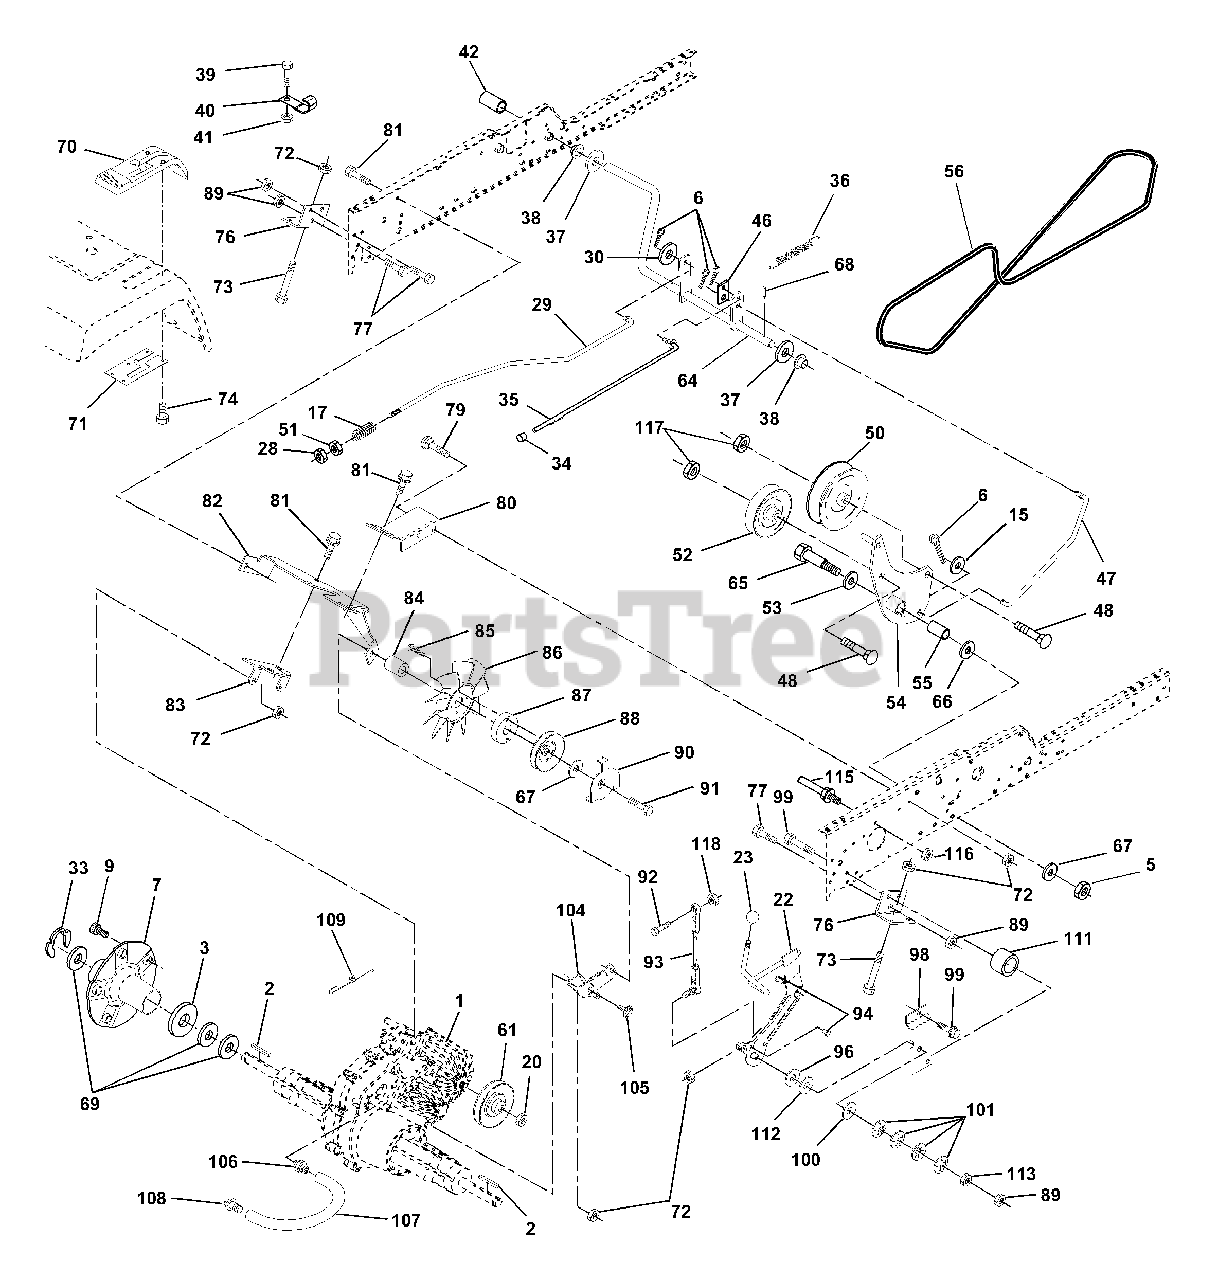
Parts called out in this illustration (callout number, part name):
2	Key 1/4 x 2.5
3	Washer Thrust Axle Harden
5	Nut Crownlock 3/8-16
6	Pin Cotter 1/8 x 3/4
7	Wheel Hub Asm.
9	Bolt Hub
15	Washer 13/32 x 13/16 x 16 Ga
17	Spring Rod Brake
20	Nut Hex Jam Toplock 1/2-20
22	Shift Arm Asm
23	Knob
28	Nut Hex Jam 3/8-16
29	Brake Rod
30	Washer 13/32 x 1 x 16 Ga.
33	Ring E
34	Cap Brake Parking
35	Rod Parking Brake
36	Spring Drive Ground
37	Washer 25/32 x 1-1/4 x 16 Gauge
38	Nyliner, Bushing
39	Screw Fin #10-24 x 1
40	Actuator Interlock Switch
41	Nut Lock #10-24
42	Cover Pedal
46	Retainer Spring
47	Clutch Rod
48	Bolt Carriage 3/8-16 x 1-1/2 Gr 5
50	Pulley Idler Flat
51	Nut Crownlock 3/8-16 UNC
52	Pulley Idler Grooved
53	Washer Hartdened
54	Clutch Arm Asm
55	Bearing, Idler
56	V-Belt
58	Bolt Fin Hex 7/16-14 x 1-1/2
61	Pullery Transaxle
64	Shaft Asm Brake Parking Clutch
65	Bolt Shoulder
66	Washer Hardened
67	Washer 13/32 x 13/16 x 12 Ga
68	Pin Roll
69	Washer
70	Console Hydro Fender
71	Plate Console Shift
72	Locknut Hex W/Washer Insert
73	Bolt Fin Hex 5/16-18 x 3
74	Screw Hex Wsh. Hi-Lo 1/4-1/2
76	Bracket Transaxle
77	Bolt Fin Hex 7/16-14 x 1
79	Bolt Carriage 5/16-18 x 5/8
80	Bracket Torque RH
81	Screw Thdrol 3/8-16 x 3/4
82	Bracket Mount Torque/Fan
83	Strap Torque Mid
84	Spacer
85	Screw #10-24 x 1-1/4
86	Fan 7" Hydro
87	Adapter Fan
88	Pulley Idler
89	Nut Crownlock 7/16-14 UNC
90	Keeper Belt
91	Screw Thdrol 3/8-16 x 2-3/4
92	Bolt Fin Hex 5/16-18 x 1.25
93	Link Shift Asm
94	Fastner Christmas Tree
96	Washer Nickel Plated
98	Bracket Shift
99	Screw Thdrol 3/8-16 x 1-1/2
100	Washer Compression
101	Washer Bellville
104	Bracket Idler
105	Screw Tap 1/4-20 x 1/2
106	O-Ring Asm Hydro Gear 70110
107	Line Fuel Hydro 15" VGT Serv
108	Cap Asm Vent Hydro Gear 70109
109	Spring Return Brake
111	Spacer Shift Lever VGTH
112	Washer Nylon High Temp
113	Nut Hex ASF 7/16-14 UNC
115	Keeper Belt T/A Gnd Dr LR
116	Nut Lock Hex Flange 5/16-18
117	Nut Lock Flg. 3/8-16 UNC
118	Nut Lock Hex w/Ins 5/16-18 UNC
